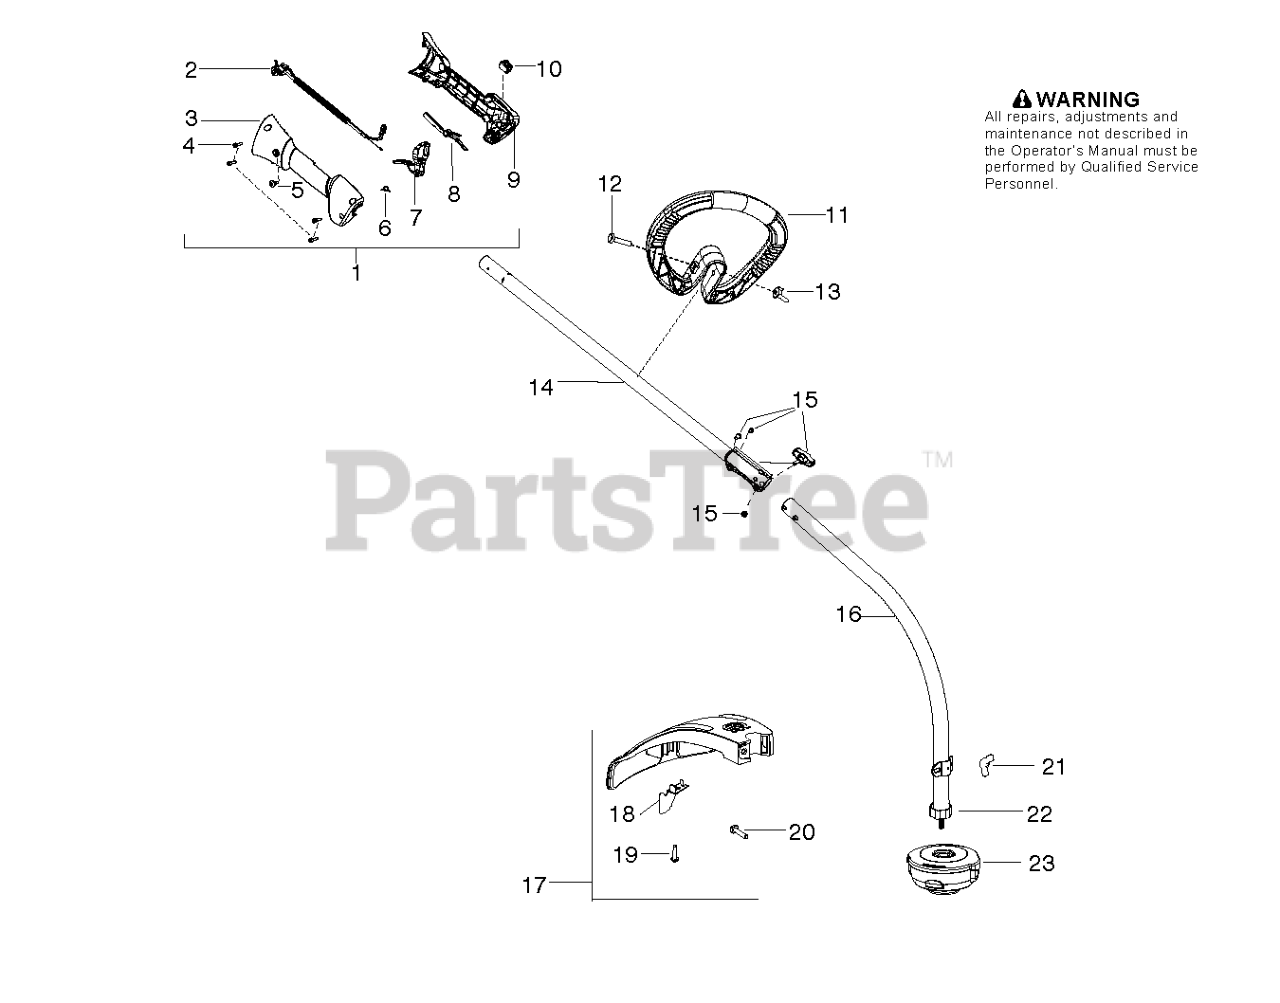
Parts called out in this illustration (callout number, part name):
1	ASSY THROTTLE HSG
2	ASSY CABLE WIRE HARNESS
3	HANDLE HALF RIGHT
4	SCREW M4 X 1.75 PT 16MM
5	SCREW M4 X 1.75 PT 16MM
6	Spring-Trigger
7	TRIGGER THROTTLE PP GOLD
9	HANDLE HALF LEFT
11	Assembly - Assist Handle
12	Bolt - 1/4-20 x 1-1/4
13	Wingnut-Handle/Shield
14	KIT UPPER BLACK
15	KIT KNOB & SCREW
16	KIT DRIVE SHAFT LOWER CD
17	KIT SHIELD
18	LINE LIMITER
19	Screw-Shroud/Blower Hsg.
20	Bolt - 1/4-20 x 1-1/4
21	Wingnut-Handle/Shield
22	DUST CUP
23	ASSY TNG P25 PP28 CLOCKWISE
